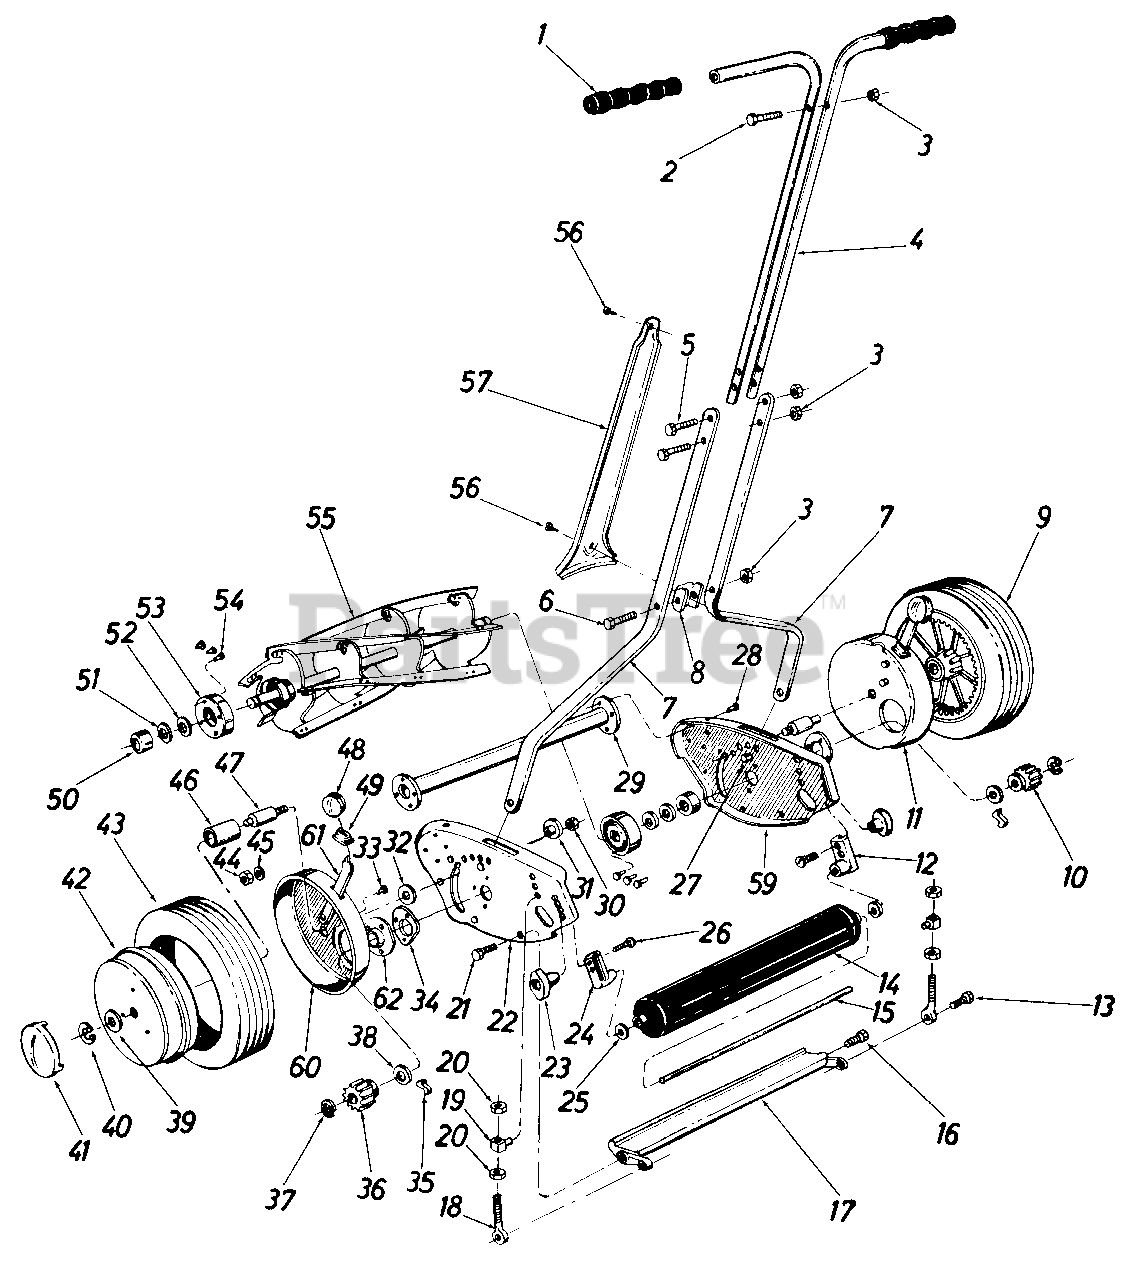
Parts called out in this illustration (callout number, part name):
1	Grip
2	Hex Scr. 5/16-18 x 1.75" Lg.
3	Hex Nut 5/16-18 Thd.
6	Hex Bolt 5/16-18 x 2.50" Lg.
7	Handle Brace
8	Spacer
9	Wheel Ass'y.-Comp.
10	Pinion Gear-R.H.
11	Gear Housing Ass'y.-R.H.
12	Roller Brkt.-R.H.
13	Screw-Rear
14	16" Roller
15	Roller Shaft
16	Screw-Cutter Bar- (L.H. Thd.)
17	Cutter Bar
18	Screw-Cutter Bar Adj.
19	Trunnion
20	Hex Nut 3/8-24 Thd.
21	Screw-Pivot- (R.H. Thd.)
22	End Plate Ass'y.-L.H.
23	Roller Adj. Knob
24	Roller Brkt.-L.H.
25	Fl-Wash. .312" I.D. x .75"O.D.
26	Roller Adj. Bolt
27	Trunnion
28	Rivet 3/16 Dia. x 3/8" Lg.
29	Spacer Tube Ass'y.
30	Hex L-Nut 5/16-24 Thd.
31	Bushing
32	Washer
33	Hex Scr. #10-32 x 3/8" Lg.
34	Retainer
36	Pinion Gear-L.H.
37	Retaining Ring
38	Felt Washer
39	Fl-Wash. .38" I.D. x 1.25" O.D.
40	Retaining Ring
41	Hub Cap
42	Wheel Ass'y.
44	Hex Nut #10-32 Thd.
45	Washer
46	Bearing
48	Knob-Wheel Adj.
49	Dust Cover
50	Beari ng
51	Felt Washer
52	Felt Washer
53	Retainer
54	Rivet 3/16 Dia. x 13132" Lg.
55	16" Reel Ass'y.
56	Ph. Hd. Scr. #10 x .38 Lg.
57	Handle Panel
59	End Plate Ass'y.-R.H.
60	Gear Housing Ass'y.-L.H.
61	Spring and Trunnion Ass'y.
62	Pinion Housing
